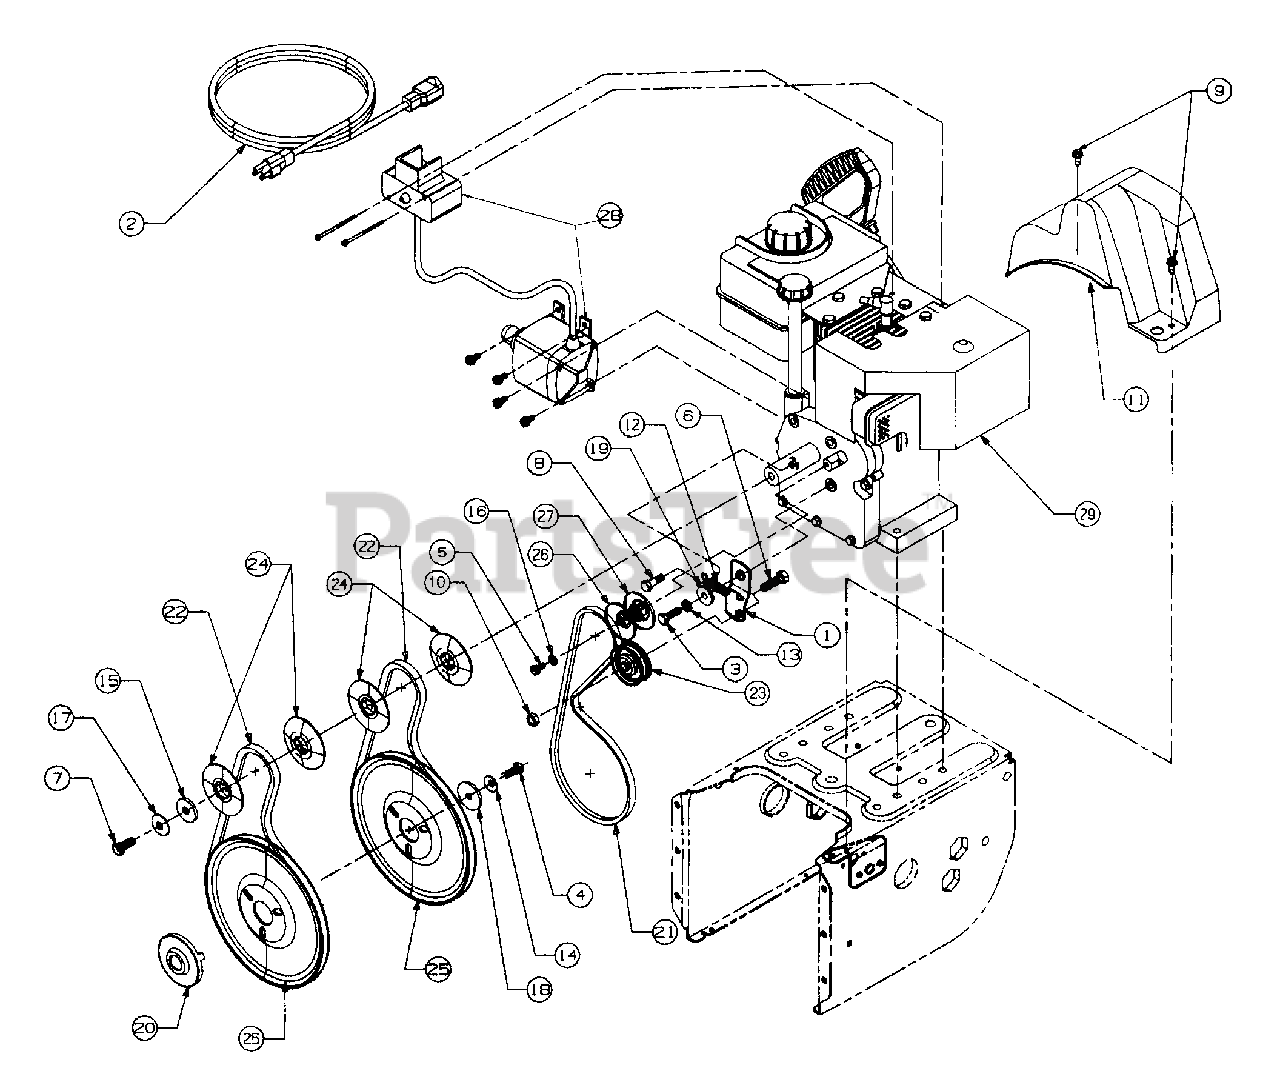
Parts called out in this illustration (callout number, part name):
3	Screw
4	Screw
5	Screw
6	Screw
7	Screw
8	Screw
9	Screw
10	Nut, Hex
11	Belt Cover
12	Spring
14	Washer - Bell
15	Washer - Flat
16	Washer - Bell
17	Washer - Bell
18	Washer - Flat
19	Shoulder Spacer
20	Pulley, Adapter
21	V-Belt
22	V-Belt Matched
23	Idler, Flat
24	Pulley, Half
25	Pulley - Auger
26	Pulley Half
27	Pulley Half
28	Starter
29	Engine
